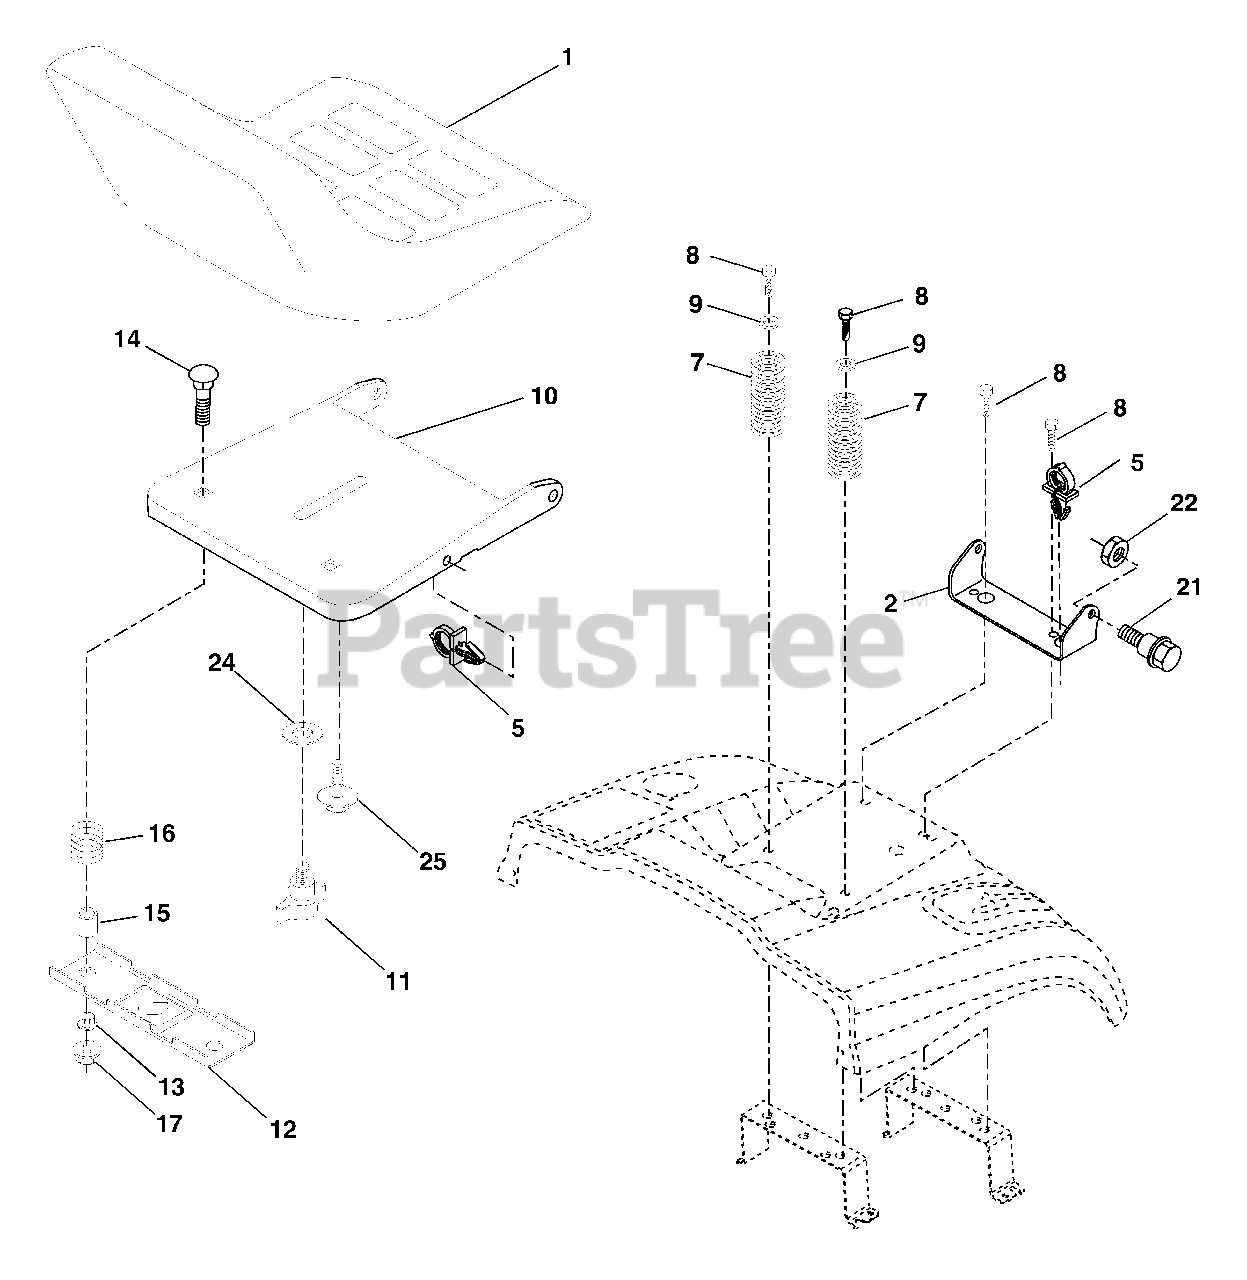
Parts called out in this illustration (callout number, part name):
1	Seat
2	Bracket Pnt Pivot Seat (blk)
5	Clip Push In Hinged
7	Spring Seat Cprsn 2 250 Blk Zi
8	Screw 3/8-16 X 1-1/2
9	Washer 13/32 X 1 X 14 Ga
10	Pan Pnt Seat (blk)
11	Knob Seat Adj. Wingnut
12	Bracket Pnt Mounting Switch
13	Bushing Snap Blk Nyl 50 Id
14	Bolt Rdhd Sht Nk 1/4-20x1-1/2
15	Spacer Split
16	Spring Cprsn Plate SW 1.310 Ga
17	Nut Lock 1/4 Lge Flg Gr 5 Zinc
21	Bolt Shoulder 5/16-18 Unc-2A
22	Nut Hex Lock w/Ins 5/16-18
24	Washer 17/32 X 1 X 12 Ga.
25	Bolt Shoulder 5/16-18 X 62
